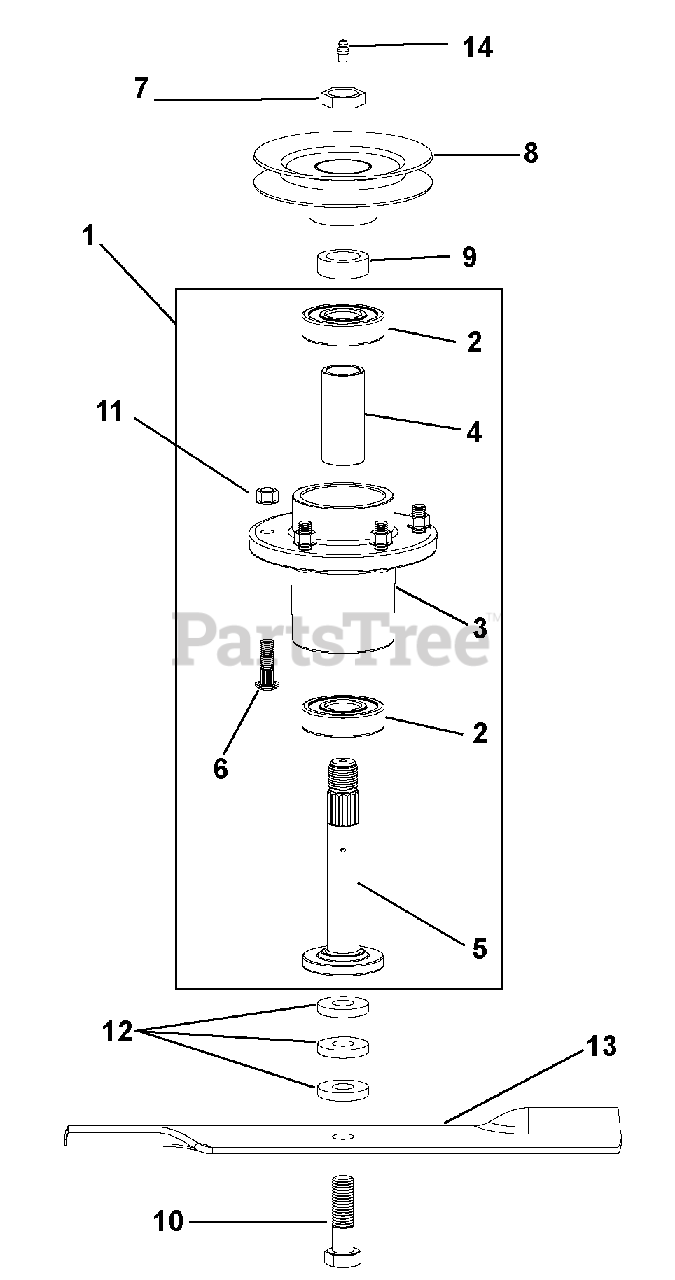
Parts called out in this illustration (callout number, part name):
1	Spindle Assembly (Includes Items 2, 3, 4, 5, 6, and 14)
2	Ball Bearing
3	Housing
4	Spacer, 1.000 x 1.250 x 2.772
5	Shaft, Spindle
6	Bolt, 3/8 x 1.25 RIB
7	Nut, Pulley (Special)
8	Pulley, Cutter Housing - Refer to "Deck Assembly" on page 18
9	Spacer, Pulley
10	Bolt, Hex .62-11 x 2.25
11	Nut, Hex .31-18
12	Spacer, Blade Bolt
13	18.0" Blade, Lift
14	Zerk, Grease S/O
